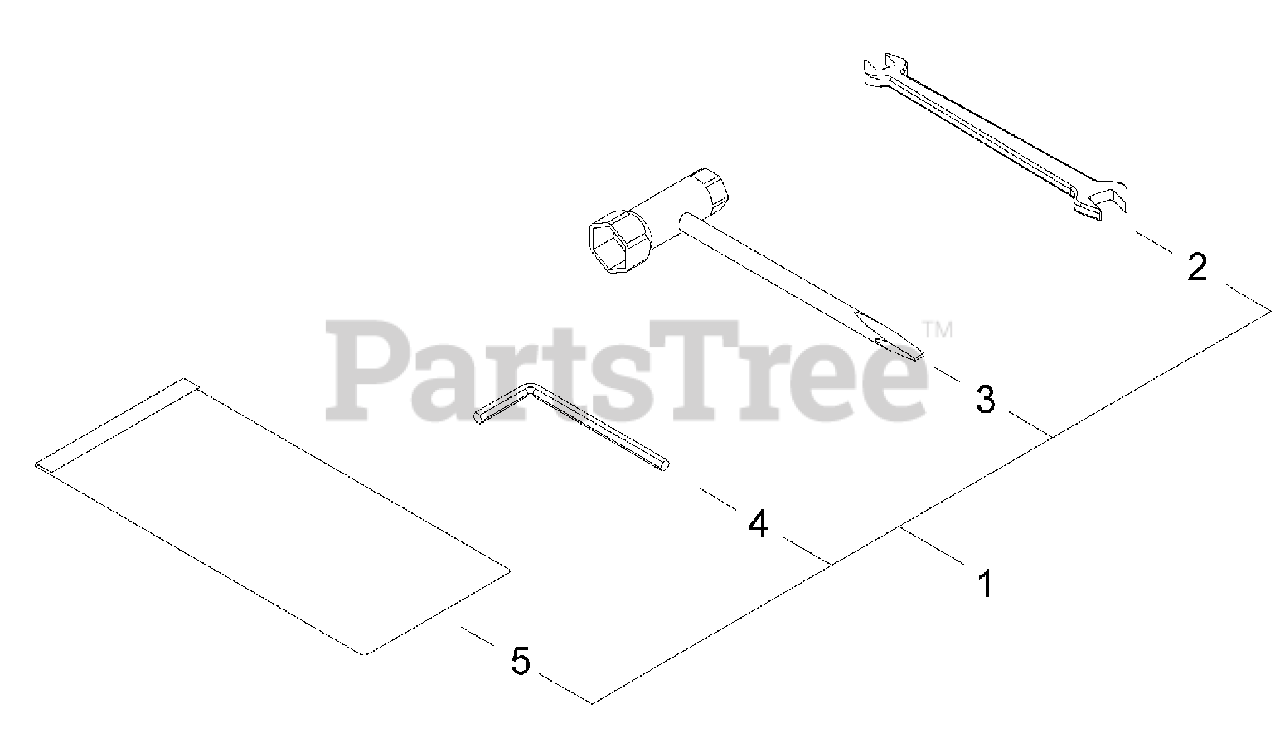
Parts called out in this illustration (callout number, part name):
1	TOOL KIT, SERVICE
2	SPANNER 8×10
3	T-WRENCH 16×13
4	WRENCH, ALLEN 4 MM
5	BAG, TOOL
